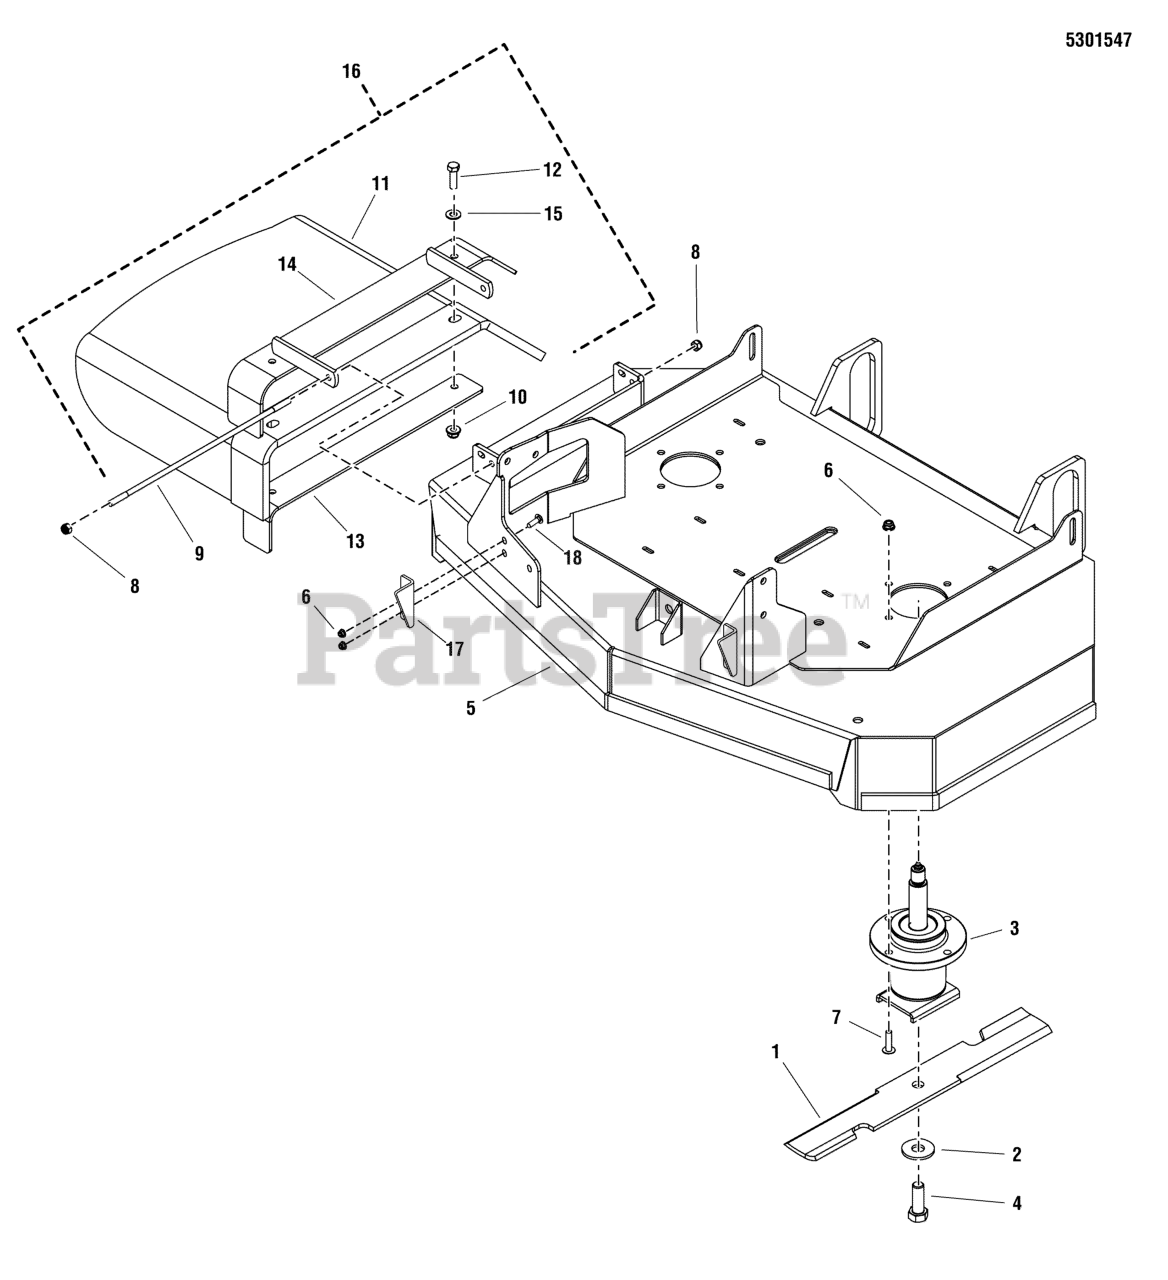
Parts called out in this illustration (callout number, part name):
1	BLADE SET, 36 DECK (2)
2	WASHER, BLADE BOLT, 9/16" F436, CZ
3	ASSM, SPINDLE, BLADE SADDLE
4	BOLT, 5/8-11 X 1-3/4 GD8
5	DECK SHELL W/ DECALS, 36, EVOLUTION
6	NUT, 5/16-18 HEX NYLOCK FLANGE
7	BOLT, 5/16-18 X 1 1/4 FLANGE
8	NUT, 5/16-24 HEX NYLON LOCK
9	ROD, 5/16 X 13.75, TBE
10	NUT, 3/8-16 HEX NYLOCK FLANGE
11	CHUTE, DISCHARGE, RUBBER
12	BOLT, 3/8-16 X 1-1/4" GD5 CZ
13	SUPPORT, DISCHARGE CHUTE, 44/48/52 - BLK
14	WELD, MOUNT, DISCHARGE CHUTE - BLK
15	WASHER, 3/8 SAE
16	DISCHARGE CHUTE ASSEMBLY
17	PLATE, DECK STOP, EVO 48 - RED
18	BOLT, 5/16-18 X 1, CARRIAGE
